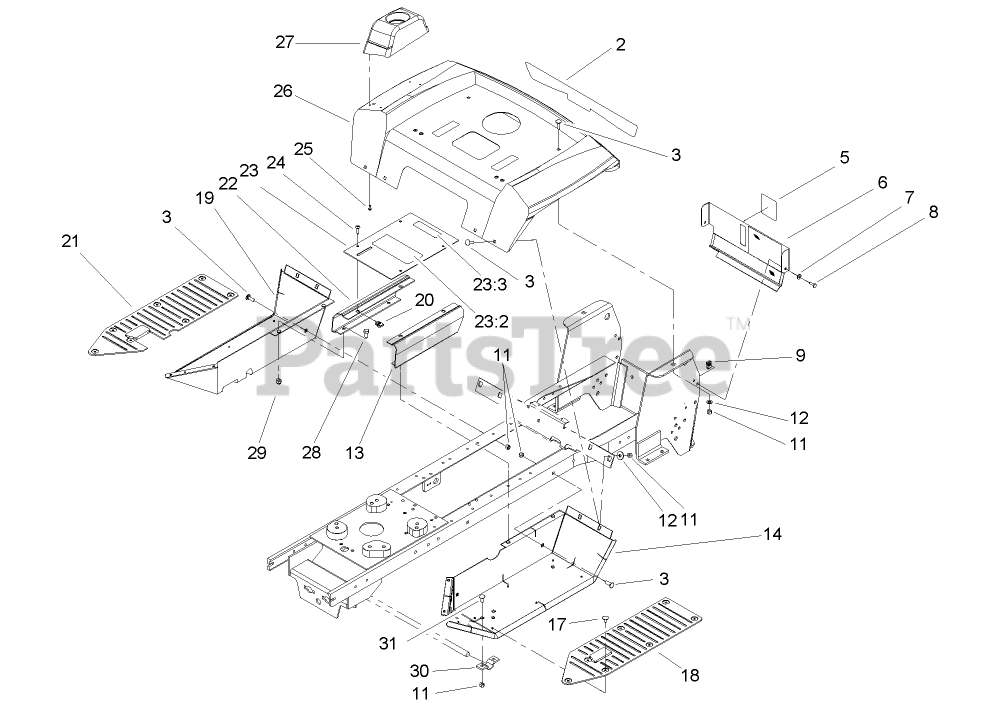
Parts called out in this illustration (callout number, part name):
2	DECAL-FENDER, REAR
3	SCREW-CARR
5	DECAL-LEVEL, FUEL
6	REAR PANEL ASM
7	WASHER-FLAT
8	SCREW-HH
9	NUT-SPEED
11	NUT-LOCK, NI
12	WASHER
13	CHANNEL-SADDLE, LH
17	FASTENER-PANEL
18	FOOTPAD-LH
19	FOOTREST-RH
21	FOOTPAD-RH
22	CHANNEL-SADDLE, RH
23	SADDLE PLATE DECAL ASM
23:2	DECAL-DANGER
23:3	DECAL-INSTRUCTION
24	SCREW-HH
25	SCREW-HWH
27	HOLDER-CUP
28	SCREW-HH
29	NUT-LOCK, NI
30	CLAMP
31	BOLT-CARR
